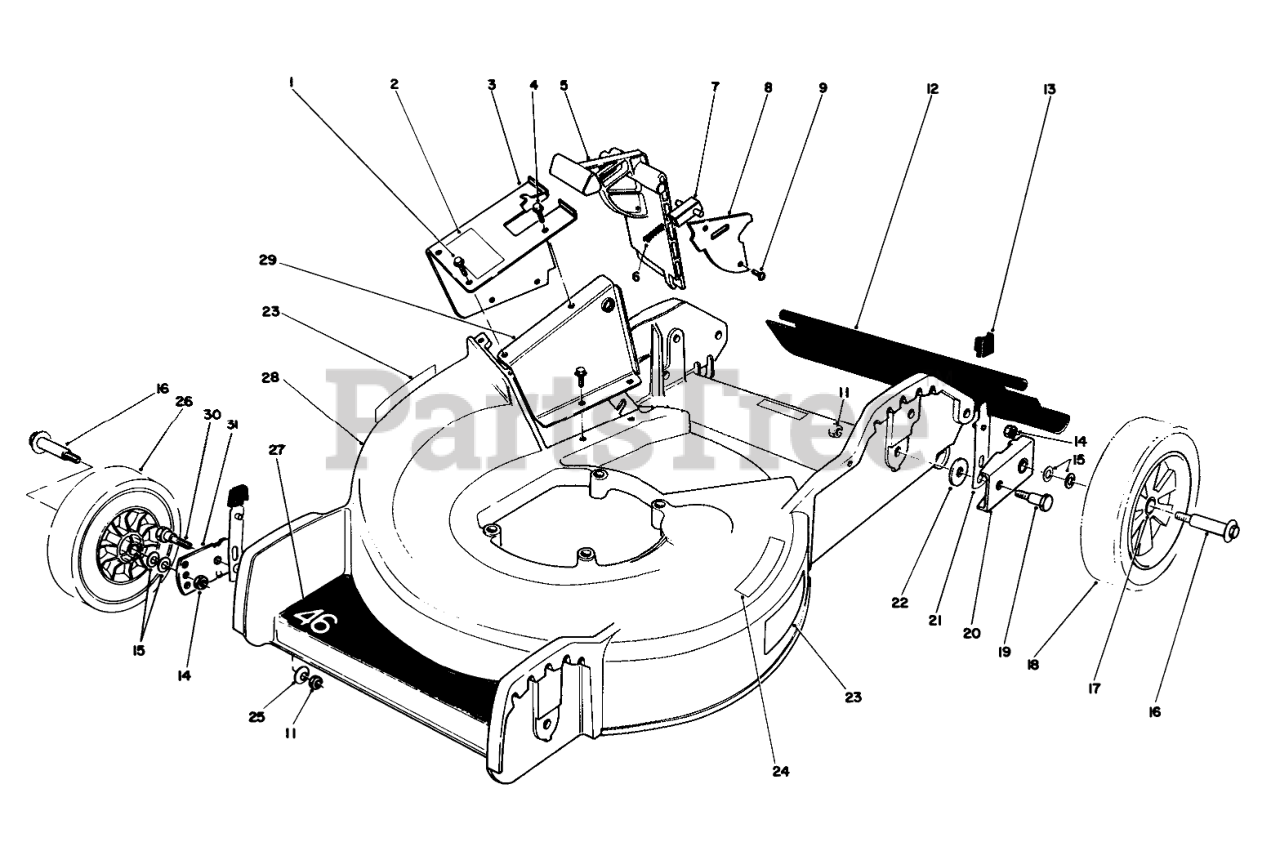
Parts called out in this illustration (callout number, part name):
1	SCREW
2	DECAL - DANGER
3	Tunnel-Outer (Incl. Ref. #2)
4	SCREW
5	Door Mulching
6	SPRING-COMPRESSION, LATCH
7	Door Latch
8	Cover Door
11	NUT-LOCK, NI
12	SHIELD - TRAILING
13	KNOB-ARM
14	Nut
15	WASHER
16	BOLT-WHEEL
17	BUSHING
18	Wheel & Tire Assembly (Incl. Ref. #17)
19	PIVOT SCREW
20	PIVOT ARM ASM
21	SPRING ARM ASM
22	PIVOT WASHER
23	Decal Danger
24	DECAL - STEP PAD INT'L
25	WASHER-BELLEVILLE
26	Wheel & Tire Assembly (Incl. Ref. #17)
27	DECAL - DECK
28	Housing (Incl. Ref. #23)
29	Tunnel-Inner
30	5/16-18 PIVOT SCREW
31	PIVOT ARM ASSY
